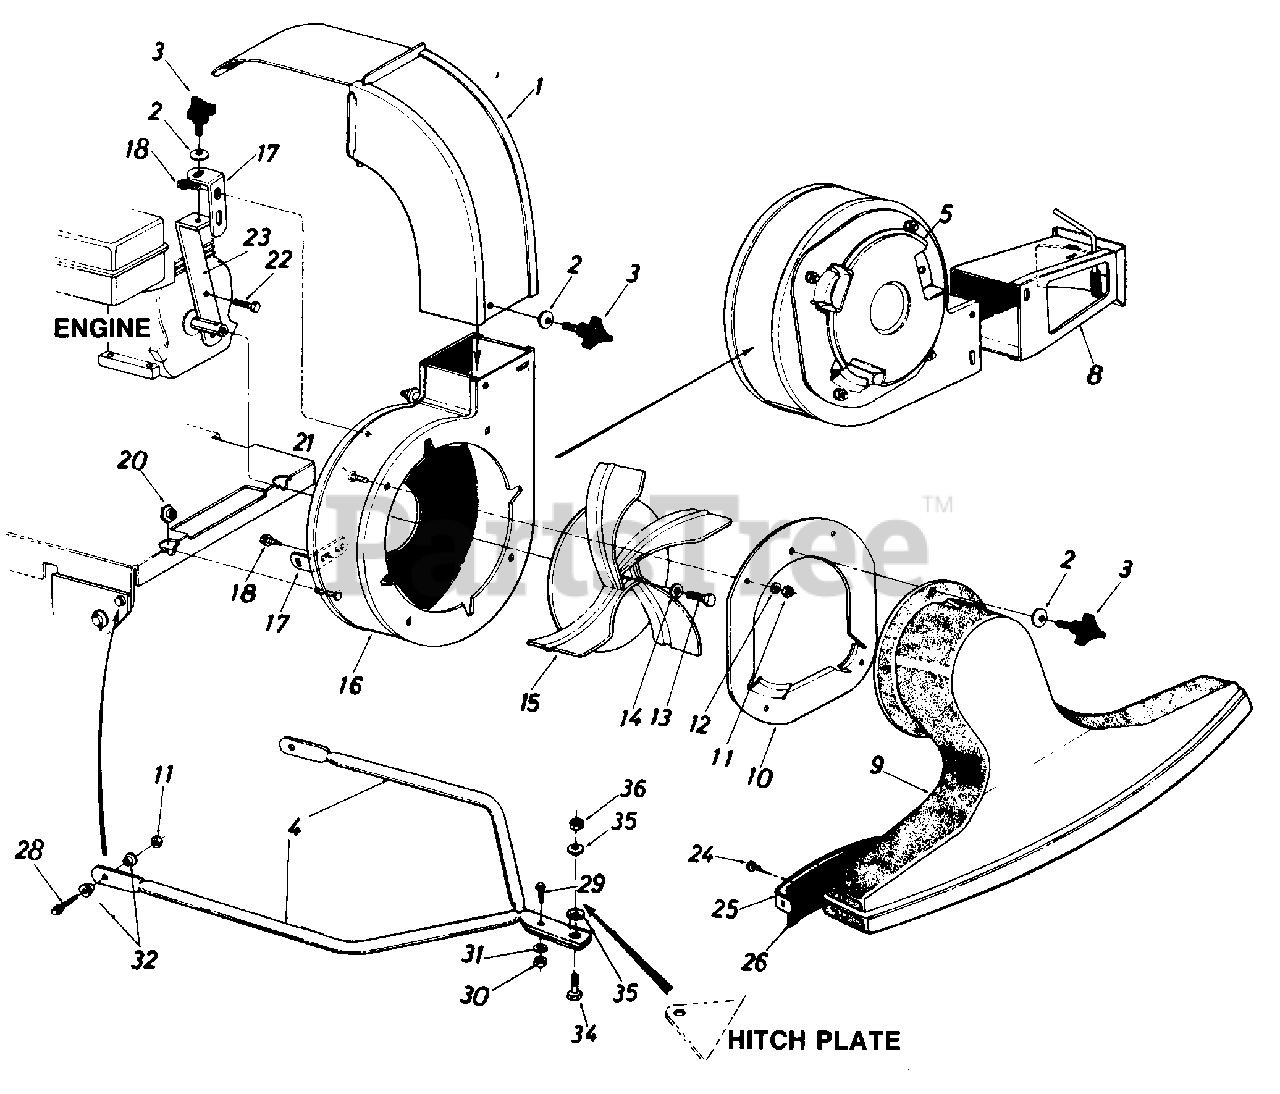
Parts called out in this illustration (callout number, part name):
3	3-Arm Thumb Scr. 5/16-18 x .75" Lg.
10	Nozzle Plate Ass'y.
11	Hex Nut 5/16-18 Thd.
12	L-Wash. 5/16" I.D.*
13	Hex Bolt 3/8-24 x 1.25" Lg.
14	L-Wash. 3/8" I.D. H.D.
15	Air Vane Plate Ass'y.
20	Hex Shoulder Nut .50 I.D.
21	Carriage Bolt 5/16-18 x .62" Lg.
22	Hex Locking Bolt 5/16-24 x .75" Lg.
28	Hex Bolt 5/16-18 x 1.00" L9.
29	Truss Mach. Scr. 1/4-20 x .75" Lg.
30	Hex Nut 1/4-20 Thd
31	L-Wash. 1/4" I.D.
32	Shoulder Spacer
34	Shld. Bolt .496 Dia.
35	Belleville Wash. .39" I.D. x 1.12" O.D.
36	Hex Jam L-Nut 3/8-26 Thd.
